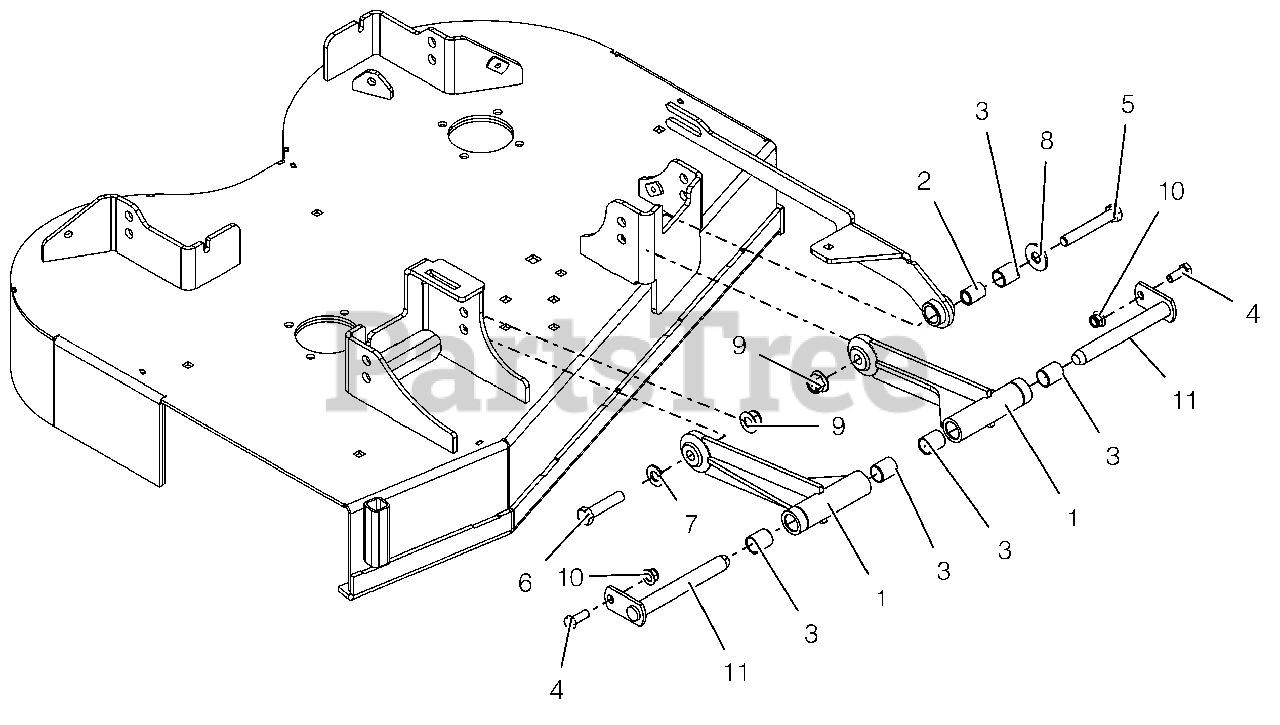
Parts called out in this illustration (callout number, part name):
1	WMT, DRAG LINK
2	BSHG, .515ID X .75ODX 1.080
3	BRG, .750 X .875 X 1.000
4	@BLT-HEX .38-16X1.00 GR5 YWZC
5	@BLT-HEX .50-13X3.25 GR5 YWZC
6	@BLT-HEX .50-13X2.25 GR5 YWZC
7	@WSHR-FL-STL.531X1.06X.095YWZC
8	@WSHR-FL-STL.563X1.38X.109YWZC
9	@NUT-LK-NYL-FLG .50-13 YWZC
10	@NUT-LK-NYL-FLG .38-16 YWZC
11	WELDMENT, MOWER MTG. PIN
